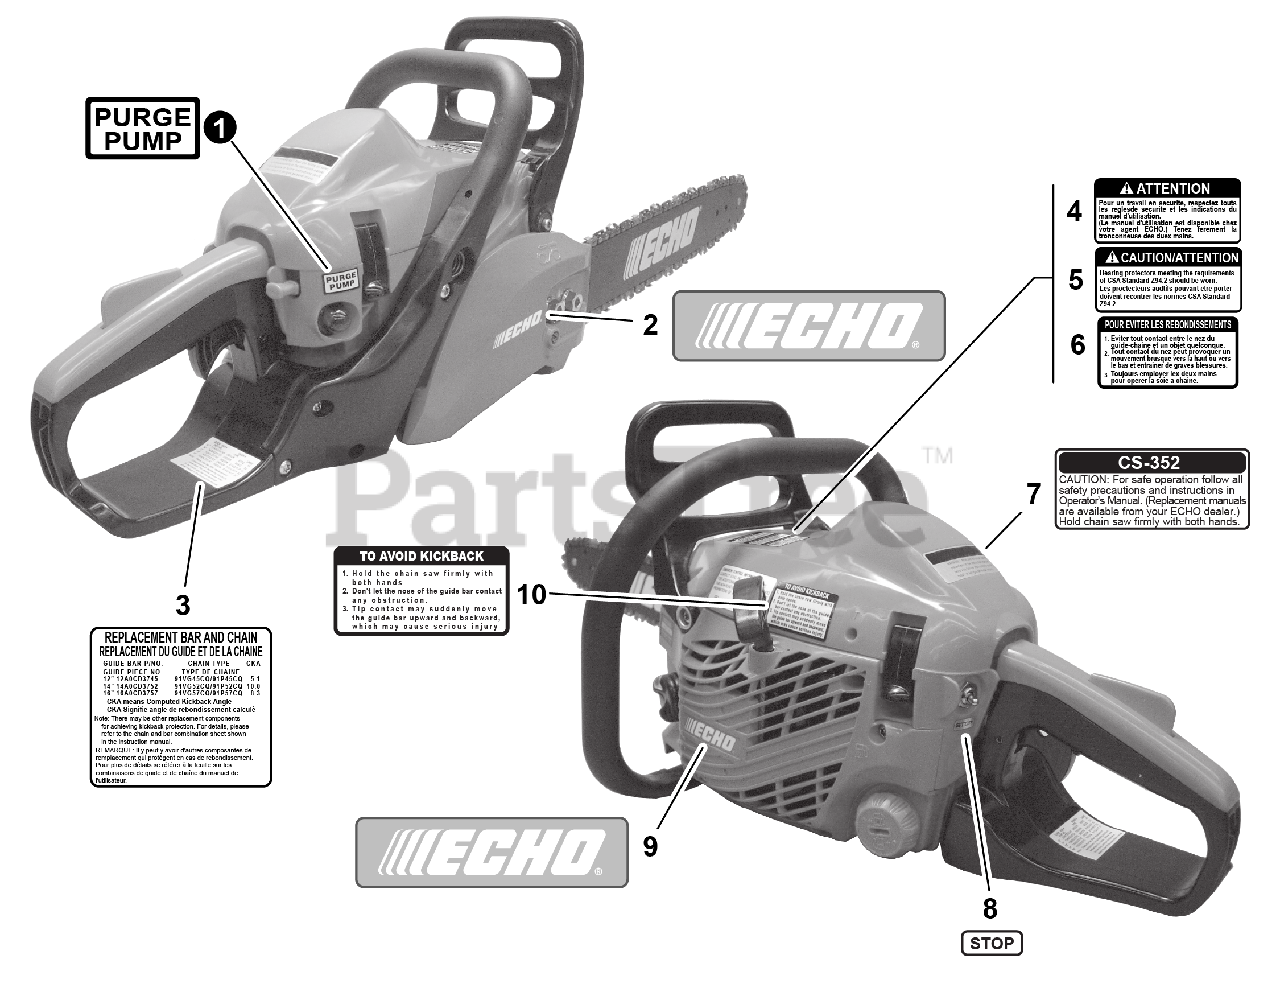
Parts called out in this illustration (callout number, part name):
1	LABEL, PURGE PUMP
2	LABEL, ECHO
3	LABEL, BAR & CHAIN
4	LABEL, ATTENTION - CANADA
5	LABEL, NOISE - ENGLISH/FRENCH
6	LABEL, KICK BACK - FRENCH
7	LABEL, CS-352 CANADA
8	LABEL, STOP
9	LABEL, ECHO
10	LABEL, KICK BACK
